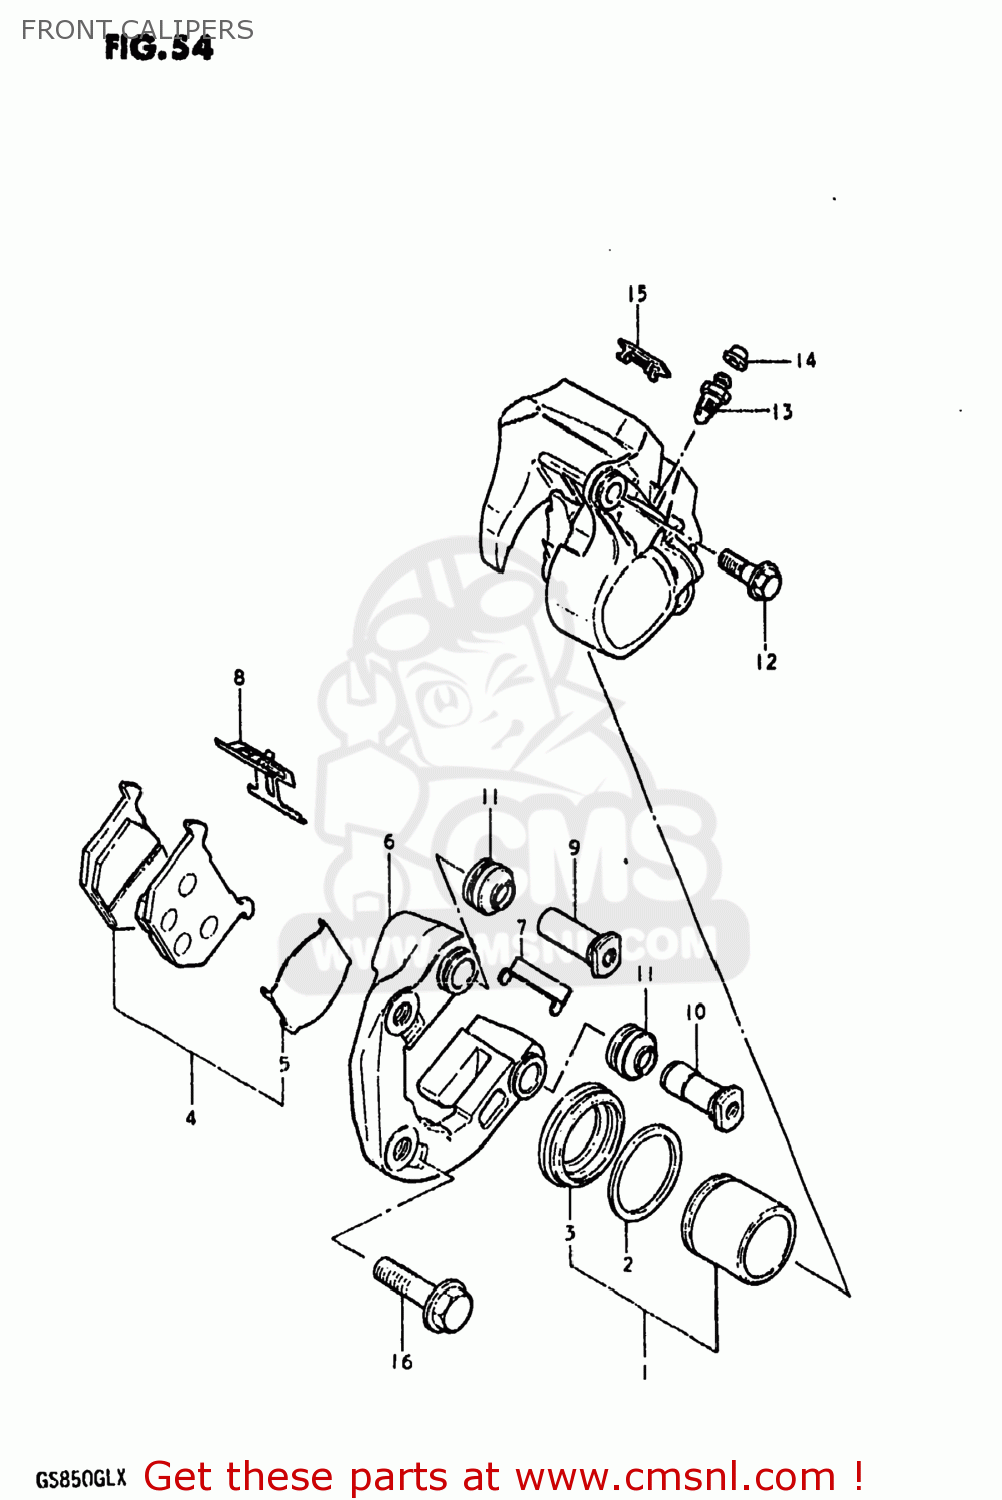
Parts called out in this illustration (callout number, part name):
0	CARIPER ASSEMBLY,RIGHT
1	PISTON SET
2	SEAL,PISTON
3	BOOT,PISTON
4	PAD SET (MCA)
5	SHIM,PAD
6	CARRIER,CALIPER,LEFT
7	GUIDE,PAD
8	SPRING,PAD
9	AXLE NO.1
10	AXLE NO.2
11	BOOT,AXLE
12	BOLT,CALIPER HOUSING
13	BLEEDER
14	CAP,BREATHER
15	COVER,INDICATOR
16	BOLT
